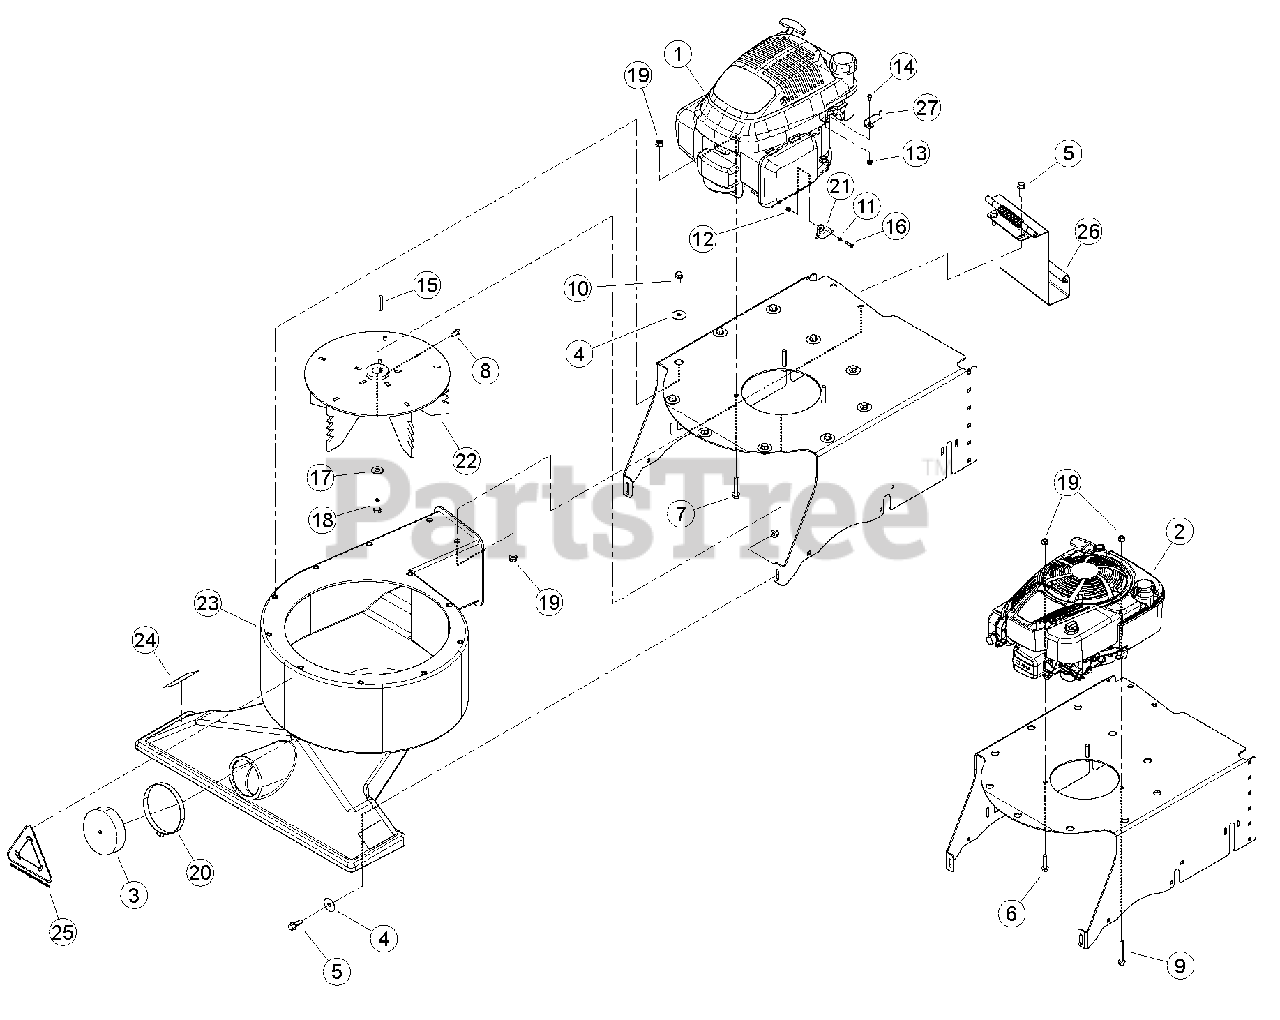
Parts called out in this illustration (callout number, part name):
1	ENGINE, 190CC B+S INTEK/IC VERTICAL (WV190 ONLY) (FOR SERVICE SEE ENGINE OWNER'S MANUAL OR YOUR NEAREST AUTHORIZED BRIGGS & STRATTON INDUSTRIAL ENGINE DEALER)
2	ENGINE, 5.5 HP HONDA GCV (WV160 ONLY) (FOR SERVICE SEE ENGINE OWNER'S MANUAL OR YOUR NEAREST AUTHORIZED HONDA INDUSTRIAL ENGINE DEALER)
3	CAP, ROUND VINYL
4	WASHER, 5/16" FENDER ZP
5	BOLT, 5/16 X 1 FLANGE NC
6	BOLT, 5/16 X 1-1/2 FLANGE NC (WV190 ONLY)
7	BOLT, 5/16 X 1-3/4 FLANGE NC (WV160 ONLY)
8	SCREW, 5/16-18 X 5/8 SQ HD SET
9	BOLT, 5/16 X 2-1/2 FLANGE NC (WV190 ONLY)
10	BOLT, 5/16 X 5/8 FLANGE NC
11	WASHER, #8 SAE (WV160 ONLY)
12	NUT, 8-32 NYLOCK (WV160 ONLY)
13	NUT, 10/24 NYLOCK TYPE NM ZP (WV160 ONLY)
14	SCREW, MCH 10-24 X 1/2" PAN HD PH ZP (WV160 ONLY)
15	KEY, SQUARE 3/16 X 1-1/2" LG PLN
16	SCREW, MCH 8-32 X 3/4 PHP RDHD (WV160 ONLY)
17	WASHER, 3/8 GR8 USS ZP
18	BOLT, 3/8 X 1" NF GR8 ZP HHCS
19	NUT, 5/16-18 NYLOCK-FLANGE
20	CLAMP, 4" HOSE
21	SWITCH, HONDA ENGINE KILL (WV160 ONLY)
22	WELDMENT, BEARVAC ROTOR
23	ASSEMBLY, FAN INTAKE HOUSING W/ DECALS
24	DECAL, DANGER
25	LOGO, COLLECT IT (WHITE)
26	ASSEMBLY, EXHAUST DOOR
27	PLATE, HONDA BRAKE HOLDER (WV160 ONLY)
